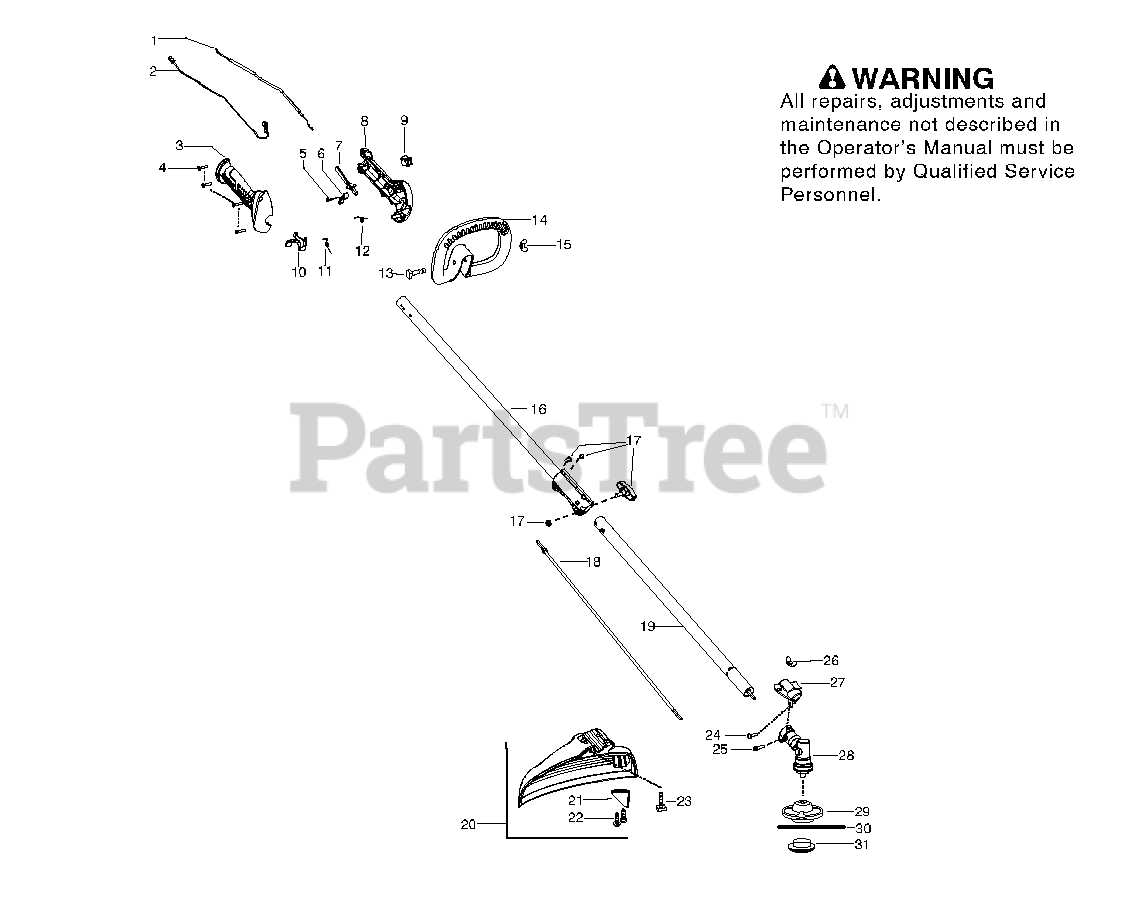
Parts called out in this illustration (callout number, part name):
2	SWITCH WIRE ASSY
3	THROTTLE HOUSING (RH)
8	THROTTLE HOUSING (LH)
11	TRIGGER SPRING
13	BOLT 1/4-20 X 2 SQUARE
14	HANDLE ASSIST 1"
15	WINGNUT, TYPE 2
16	KIT
17	ASSY COUPLER BLACK
18	Flex Shaft
19	KIT SHAFT LOWER SST BLACK
20	KIT SHIELD DOM NO BLADE
21	LINE CUTTER
23	BOLT, TYPE 2
24	SCREW 8-16 X 9/16 (PLAS
25	SCREW - CARB. ADAPTOR
26	WINGNUT, TYPE 2
28	GEARBOX 1
29	ASSY FIXED LINE HEAD
30	LINE FOR WT3100.080" PP325.115
31	CAP FIXED LINE
